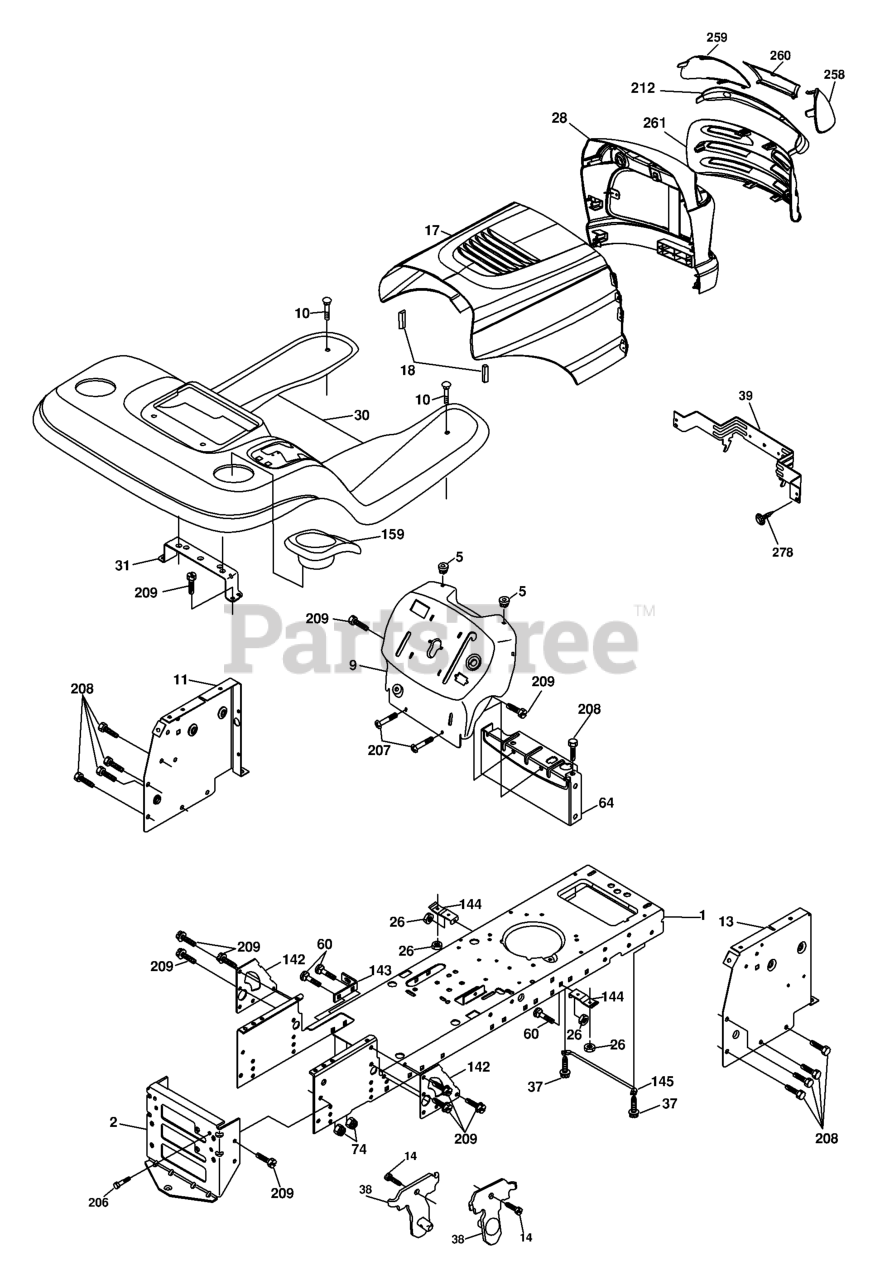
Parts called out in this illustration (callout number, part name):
1	CHASSIS STAMPING
2	DRAWBAR, 12GA
5	BUMPER.RUBBER.HOOD
9	DASH
10	BOLT D
11	PANEL.DASH.LH.LTX
13	PANEL DASH RH
14	SCREW LT
17	HOOD
18	BUMPER.HOOD.LARGE.1.75"
26	NUT
28	GRILL/LEN.ASM.DL.HUSQ
30	FEND/FTREST.STL.W/CPH
31	BRACKET.SUPPORT.FENDER
37	Screw Thdrol 6/16-18 x 1/2 TYT
38	BRACKET.ASM.PIVOT.MOWER.REAR
39	BRACKET PIVOT LASER
60	Bolt RDHD Sqnk 3/8-16 unc x 3/4
64	DASH LOWER
142	PLATE REINFORCEMENT
143	BRACKET, SWAYBAR CHASSIS
144	BRKT, FOOT REST
145	ROD PIVOT CHASSIS/HOOD
159	CUPHOLDER
206	SHOULDER BOLT 5/16-18TT
207	SCREW, 5/16-18 X 1/2
208	Screw Thdrl 3/8-16 x 1/2
209	SCREW, 3/8-16X3/4
212	INSERT.LENS.REFLECTIVE
258	LENS LH
259	LENS LH
260	COVER.LENS.HUSQ.( HAVE GRAY)
261	INSERT GRILLE
278	SCREW
